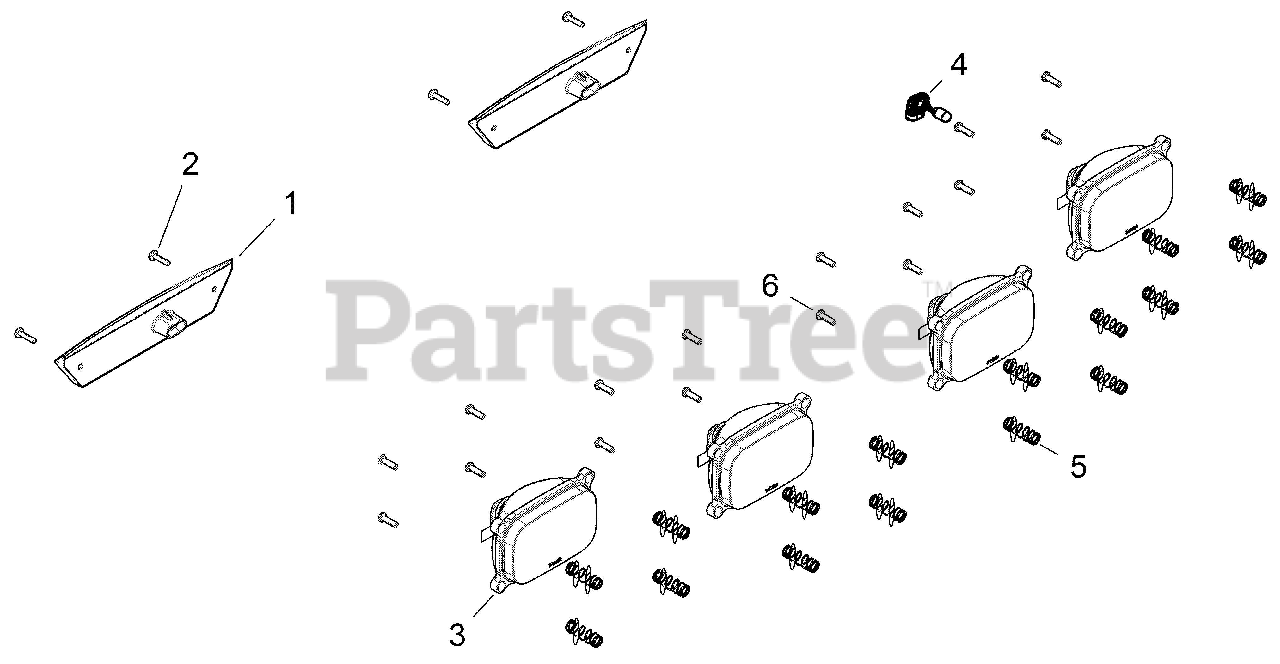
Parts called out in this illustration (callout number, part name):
1	ASM-TAILLIGHT
3	ASM-HEADLIGHT
4	BULB, HEADLIGHT, 50W
5	SPRING, HEADLIGHT
